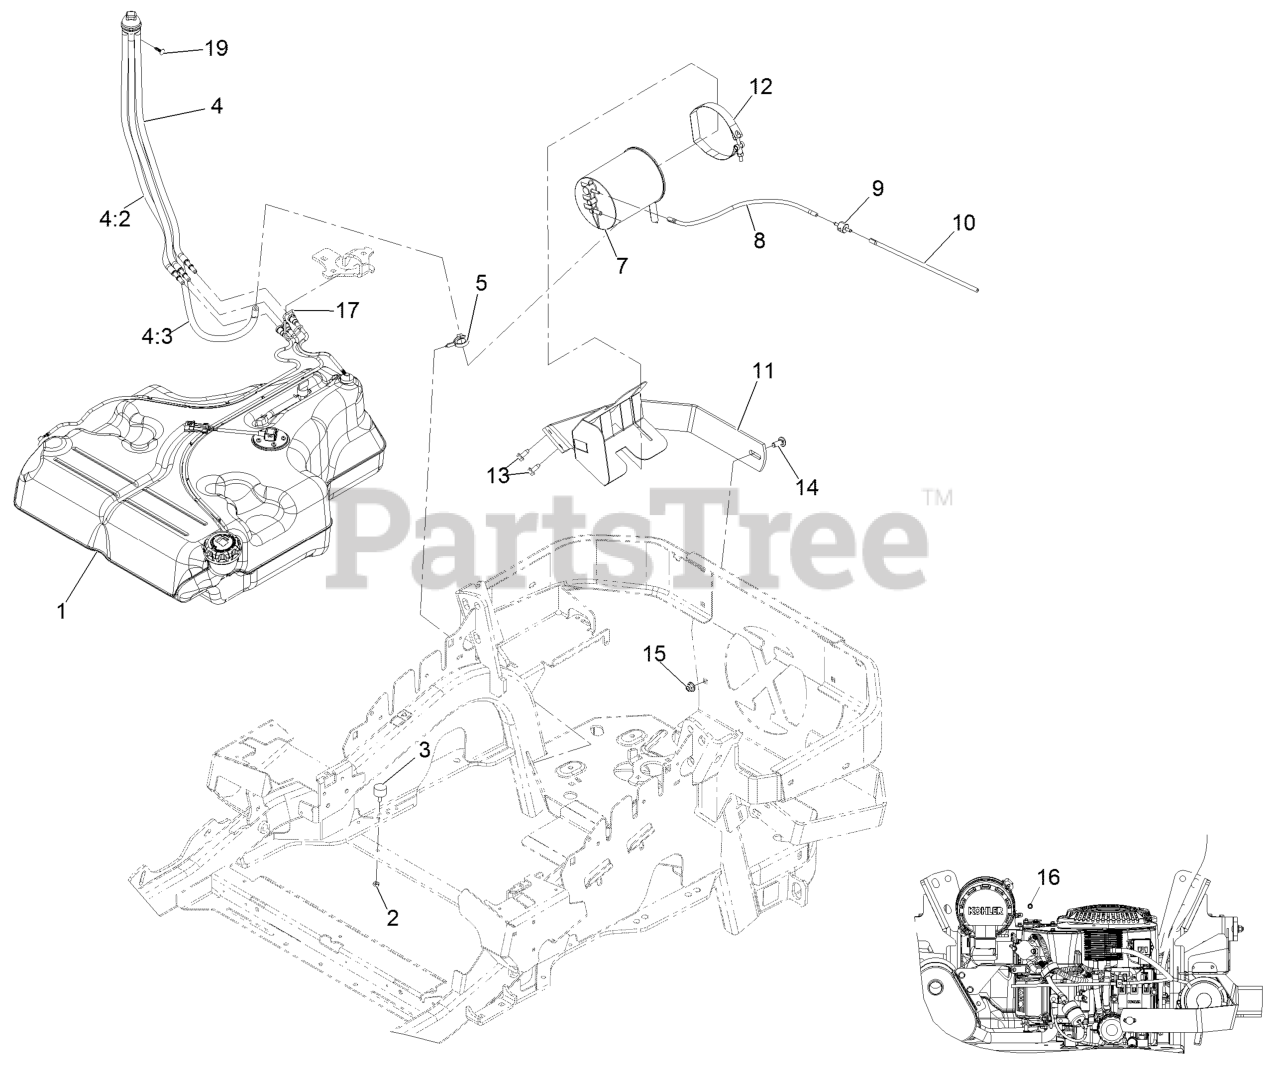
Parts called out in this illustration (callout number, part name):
1	ASM-12 Gal Fuel Tank, Low Perm
2	Nut-Jam 1/4-20
3	Bumper-Rubber (W/ Stud)
4	Fuel Manifold Vent ASM
4:2	Hose-Fuel Line 24"
4:3	Hose-Fuel
5	Clamp-Hose
7	Canister-Carbon, 1200Cc
8	Hose-Vent, Formed
9	Valve-Check, Vacuum
10	Hose-Vent, Formed
11	Mount-Canister
12	Clamp-T-Bolt
13	Screw-HWH 5/16-18 X 3/4 Tf
14	Bolt-Carriage 3/8-16 X 1
15	Nut-Nyloc 3/8-16 Flg
16	Plug-Port
17	Retainer-Line, Vapor
19	Plug-Plastic
